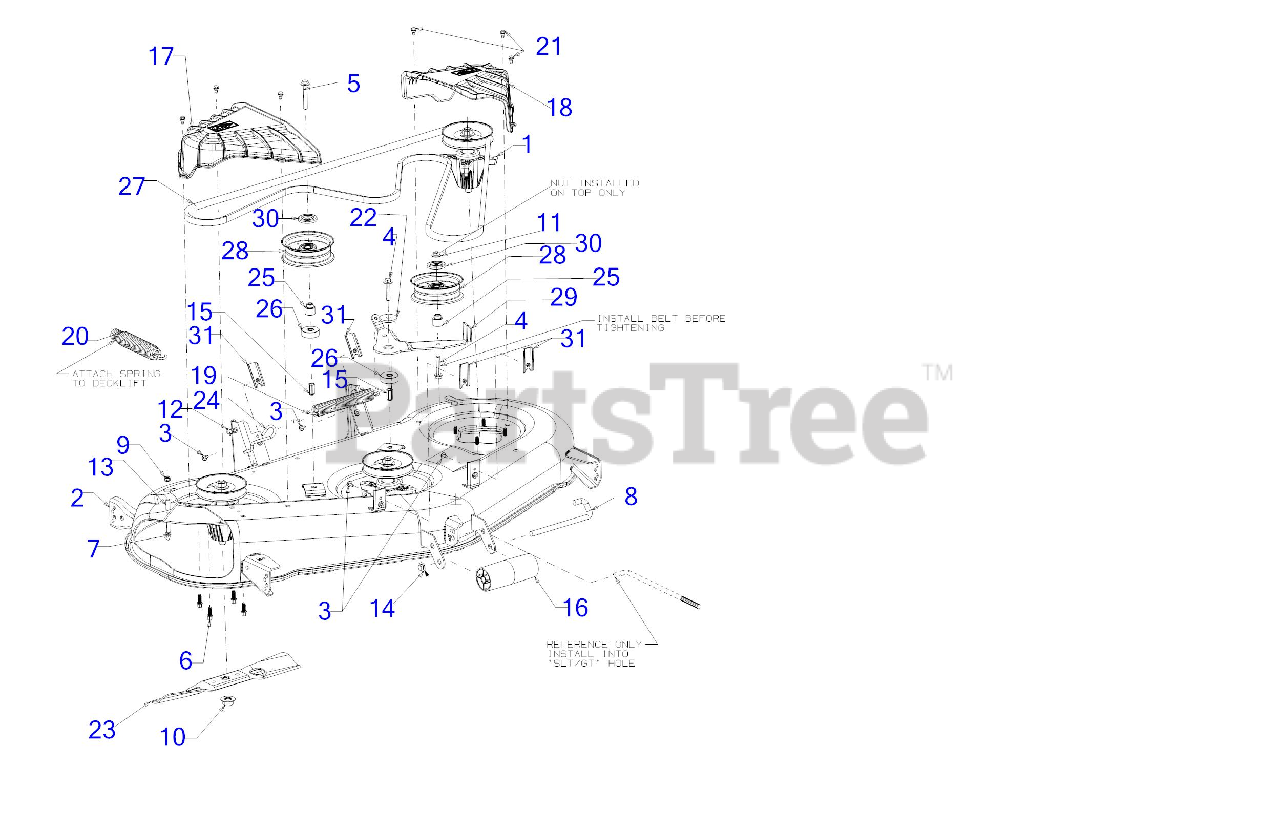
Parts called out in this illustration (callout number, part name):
1	SPINDLE ASSEMBLY
1	Cub Cadet 50" SPINDLE ASSEMBLY (06980)
3	SCREW M6-1 x .625
4	SCREW 3/8-16 x 2.0
5	SCREW 3/8-16 x 2.75 GR5
6	SCREW 5/16-18 X .875
7	SCREW 5/16-18 x 1.5 LG
8	ROLLER PIN 1/2 x 7.31
9	FLANGE LOCK NUT 5/16-18
11	FLANGE LOCK NUT
12	BOW TIE COTTER PIN
15	NUT RIVET 3/8-16
17	SPINDLE COVER (RH)
18	SPINDLE COVER (LH)
19	EXTENSION SPRING
20	LIFT ASSIST SPRING
21	SHOULDER SCREW 1/4-20 x .50
22	SHOULDER SPACER
23	17.27" BLADE (2N1)
23	Cub Cadet 50" HI LIFT BLADE SET
23	Genuine Factory Parts 50" BLADE SET
23	50" 6 PT STAR LOW LIFT/SAND BLADE
23	Cub Cadet 50" LOWLIFT BLADE SET
23	Genuine Factory Parts 50" LOWLIFT BLADE SET
23	50" 6 PT STAR XTREME MULCH BLADE
23	Cub Cadet 50" XTREME BLADE SET
23	Genuine Factory Parts 50" XTREME MULCH BLADE SET
24	DECK SPRING HOOK
25	SHOULDER SPACER
26	SPACER .385ID x 1.75OD x .585THK
27	V-BELT B SEC x 134
27	Cub Cadet 50" DECK BELT
27	Genuine Factory Parts 50" DECK BELT
28	IDLER PULLEY 4.50" DIA
29	IDLER PIVOT BRACKET
30	IDLER PULLEY CAP
